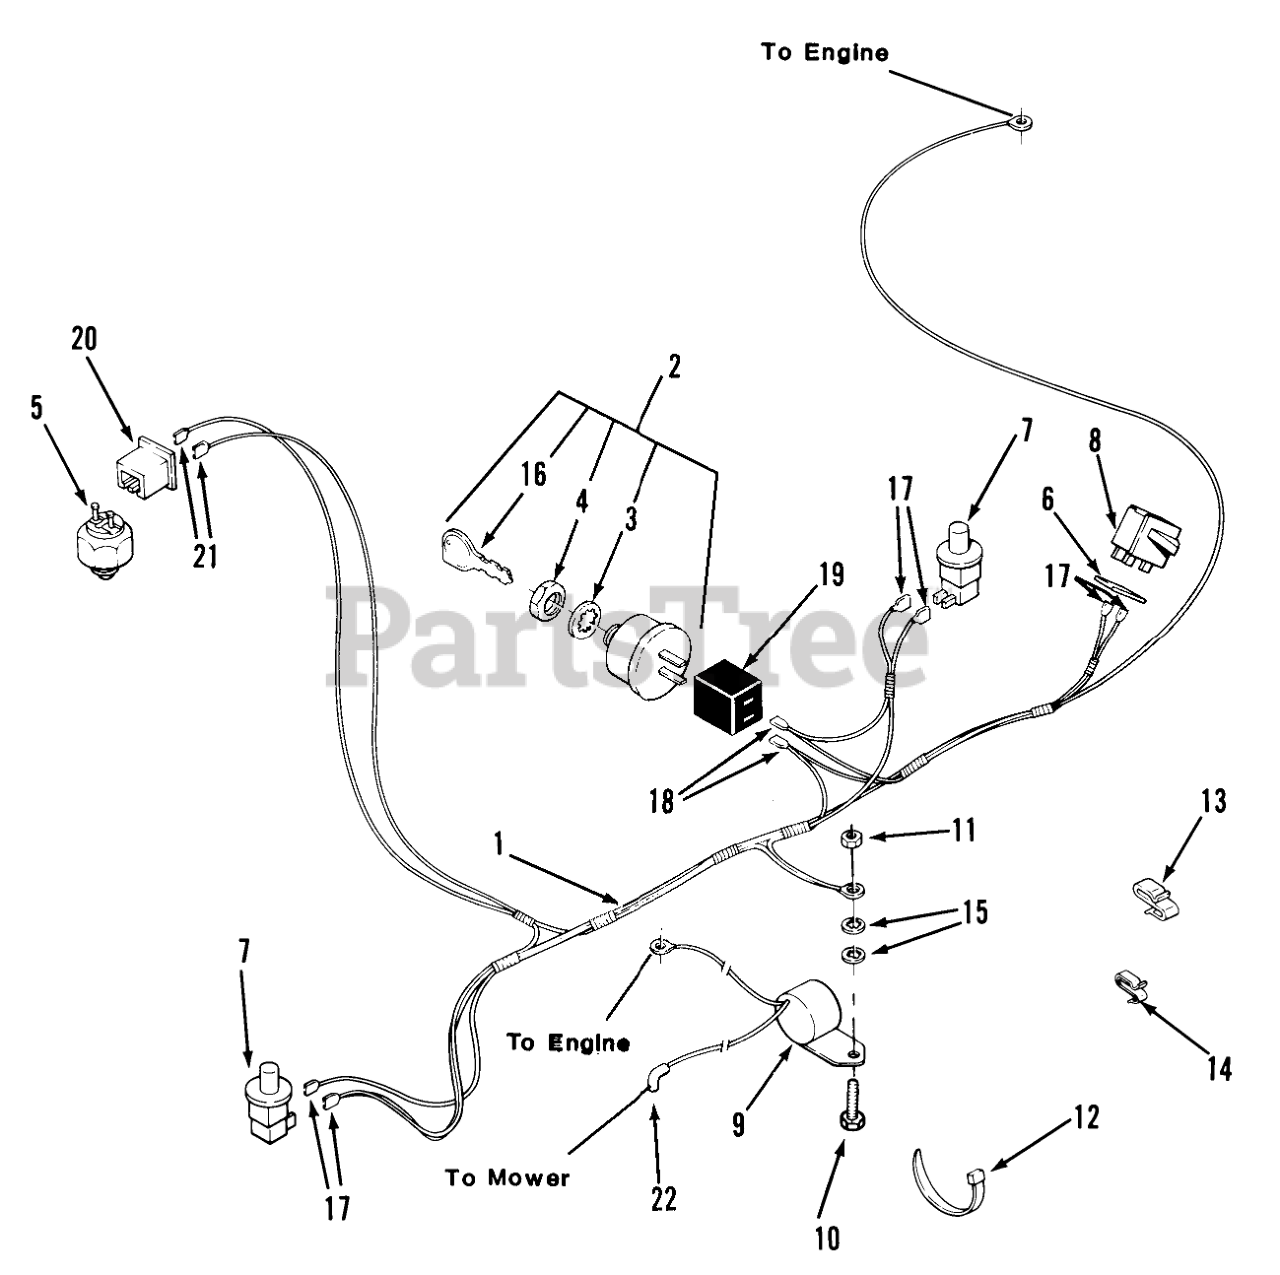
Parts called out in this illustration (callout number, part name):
1	WIRING HARNESS
2	SWITCH-IGNITION
3	LOCKWASHER
5	SWITCH-INTERLOK CLUT
6	SHIELD-DIRT SPST
7	SWITCH (N.C.)
8	SWITCH
9	INTERLOCK MODULE
10	Screw
11	Nut
12	PLASTIC TIE
13	CLIP-CABLE
14	SPEED CLIP
15	Washer-Lock
16	Key-EL
17	Terminal
18	TERMINAL-TAB RCPT
19	Conn. Body-Part of 2
20	Connector Housing M
21	Terminal
22	Terminal Part of 5
